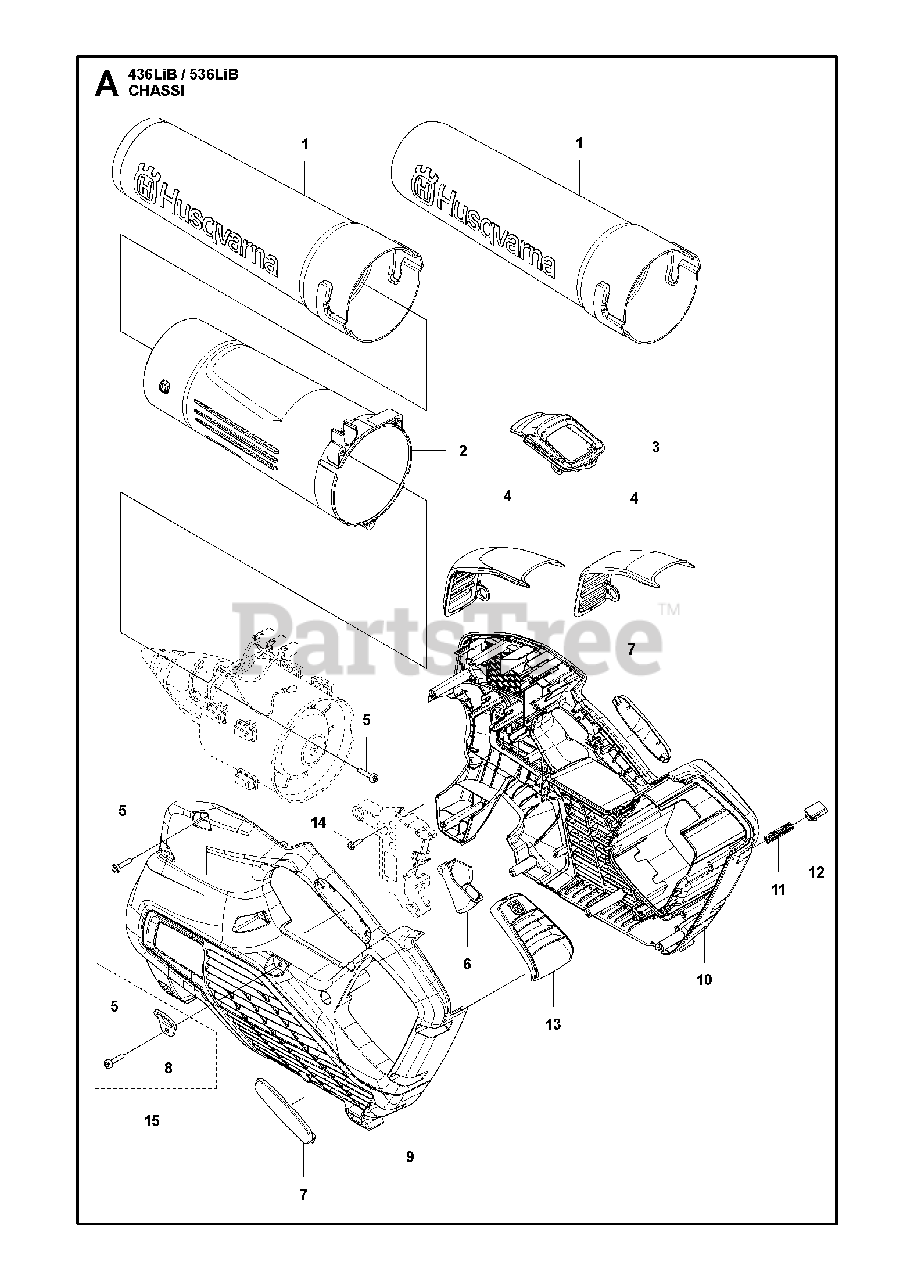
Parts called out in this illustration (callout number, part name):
1	NOZZLE 436LIB
1	TUBE ASSY
2	TUBE FAN OUTLET
3	FRAME KEYPAD
4	COVER
5	SCREW
6	THROTTLE CONTROL
7	HANDLE INSERT GREY
8	EYELET
9	HOUSING LEFT B1
10	HOUSING RIGHT B1
11	SPRING PUSH OUT
12	PUSH BUTTON
15	KIT EYELET
